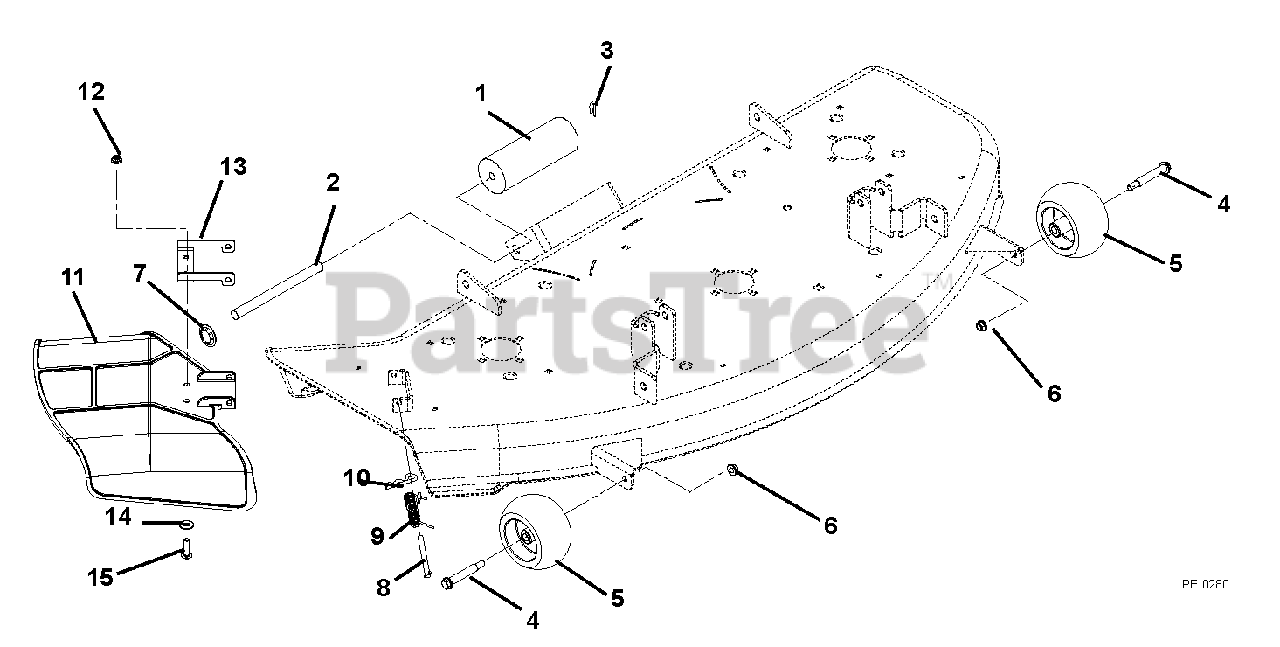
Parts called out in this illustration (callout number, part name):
1	Roller (104, 106, 116)
2	Pin, Roller (104, 106, 116)
3	Pin, Spring Clip (104, 106, 116)
4	Bolt, Shoulder .38-16 x 2.50 Hex Washer Head Grade 5
5	Wheel 5 x 3
6	Nut, Locking-Top-Flange .38-16
7	Push Nut, .625 Shaft (104, 106, 116)
8	Clevis Pin
9	Spring, Torsion
10	Pin, Hair .08 x .18 x 1.18
11	Plastic Chute
12	Nut, Locking, Top Flange .31-18
13	Chute Reinforcement
14	Washer, Flat Steel .38 x .875 x .083
15	Screw, Socket Head, Button Head .31-18 x .75
